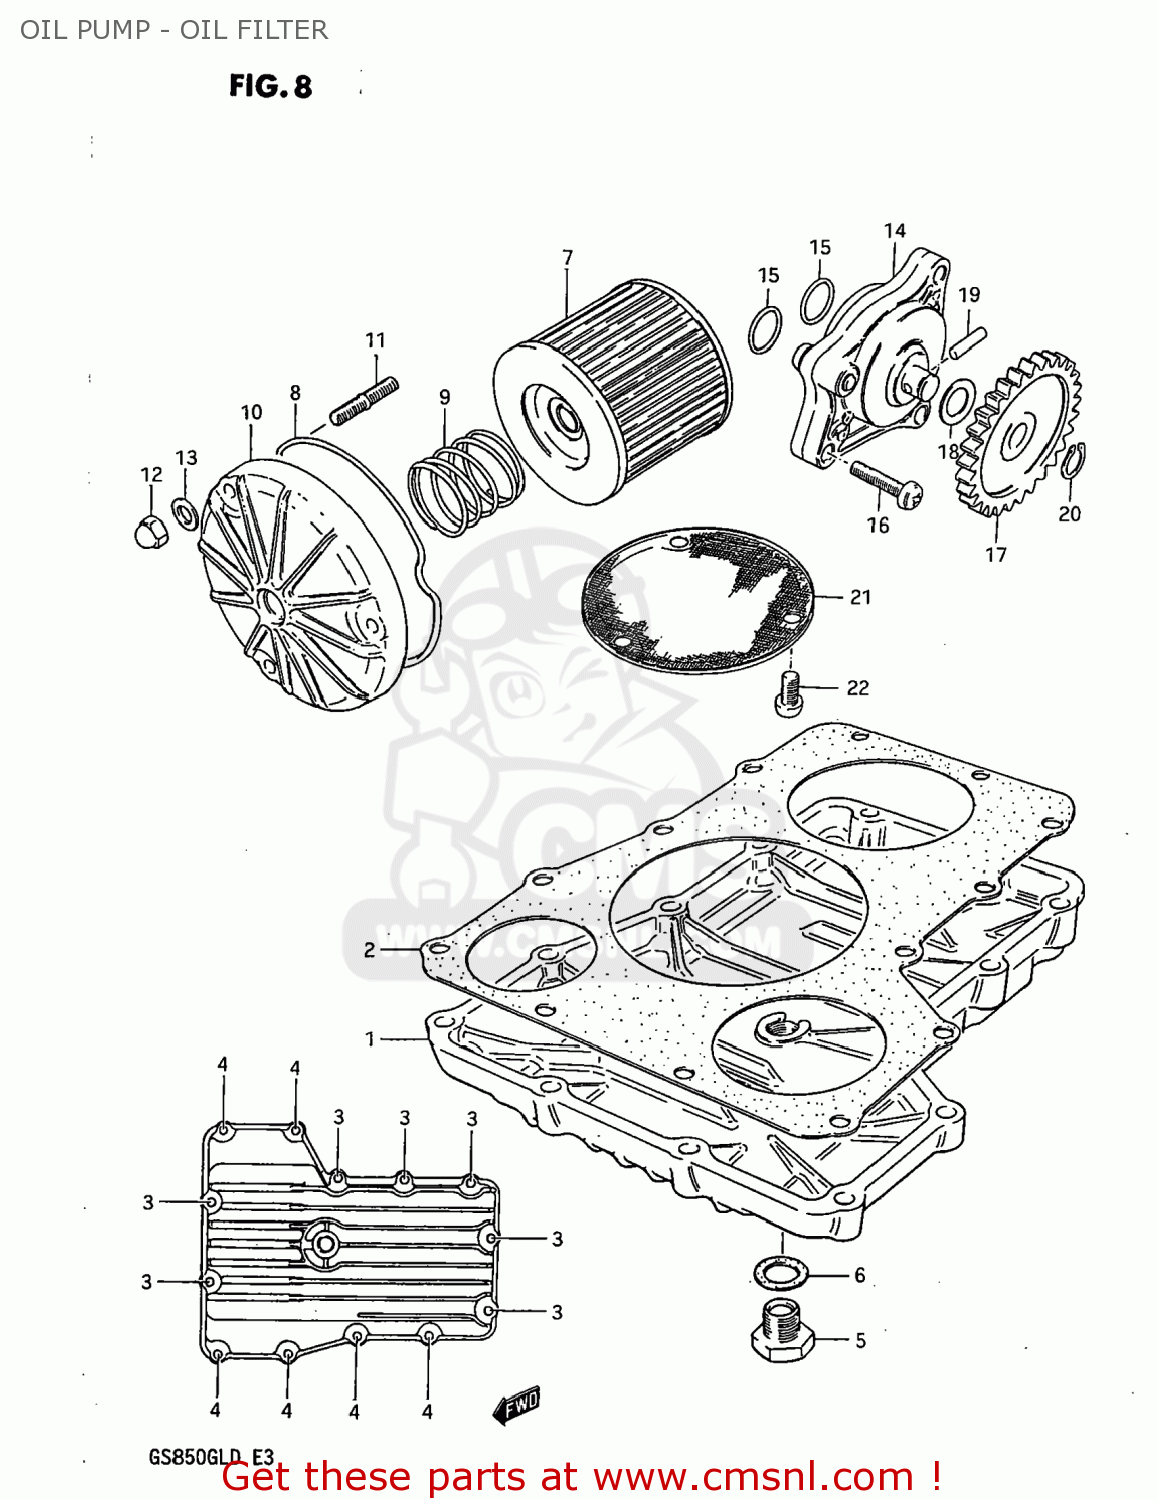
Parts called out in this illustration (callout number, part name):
1	PAN,OIL
2	GASKET,OIL PAN (MCA)
3	BOLT
4	BOLT
5	PLUG
6	GASKET(14X19.2X2) (NAS)
7	FILTER ASSY,ENGINE OIL
8	O RING,OIL FILTER CHAMBER CAP
9	SPRING
10	CAP,OIL FILTER
11	STUD 6X20
12	NUT
13	WASHER
14	PUMP ASSEMBLY,ENGINE OIL
15	O RING(D:1.9,ID:13)
16	SCREW
17	GEAR,ENG OIL PUMP DRIVEN(NT:33
18	SHIM
19	PIN(4X15.8)
20	CIRCLIP
21	STRAINER,ENGINE OIL
22	SCREW 6X12
